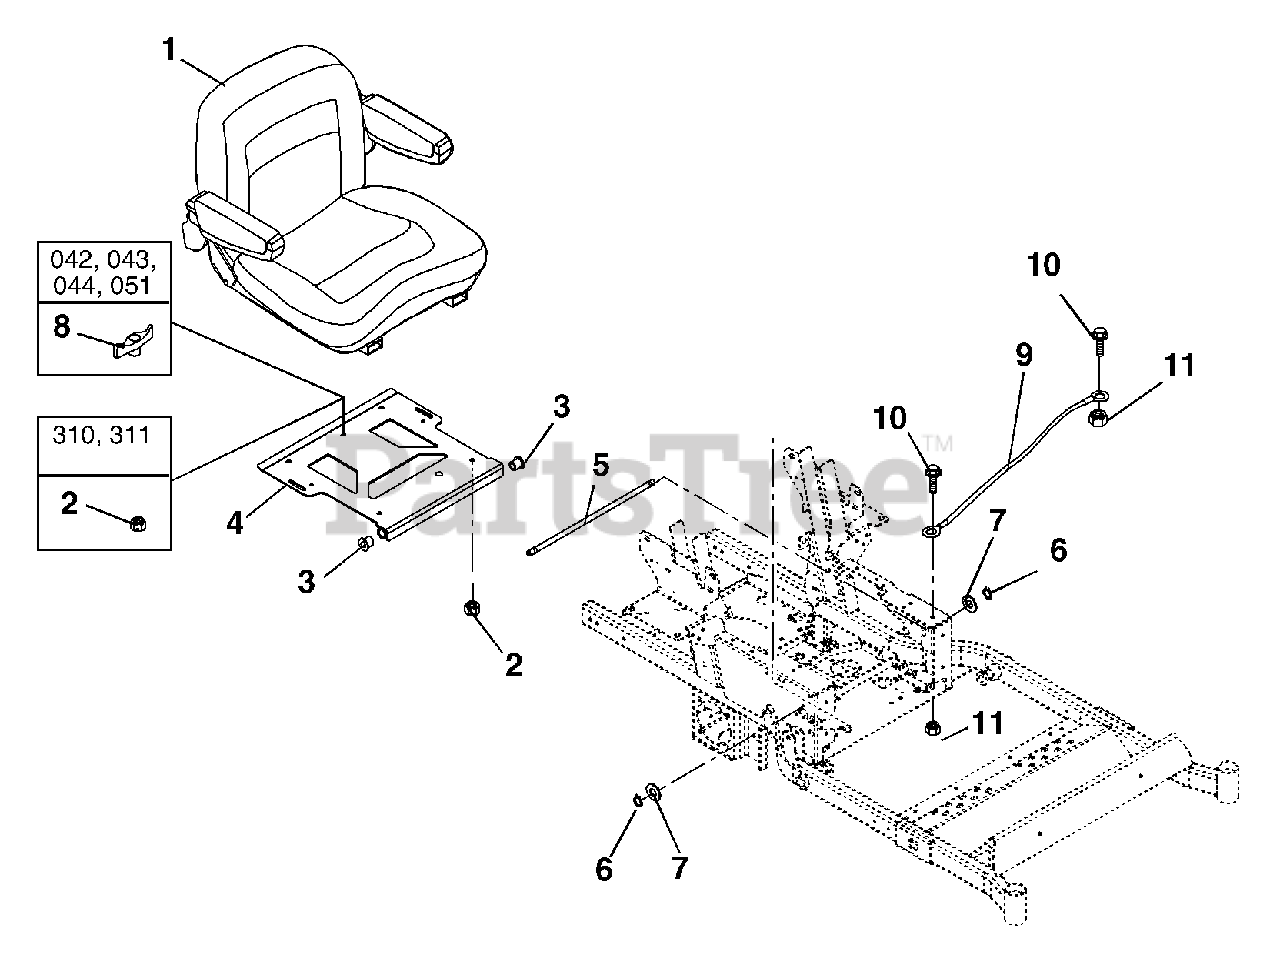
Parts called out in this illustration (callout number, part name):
2	Nut-Locking-Top-Flange .31-18 (042, 043, 044, 051)
2	Nut-Locking-Top-Flange .31-18 (310, 311)
3	Bushing-Flange .515 x .750 x .745 x 1.00
4	Seat Pivot Mount
5	Rod, Seat Frame Pivot
6	Ring-Retaining-External .500 x .050
7	Washer-Flat-Steel .531 x 1.06 x .095
8	Knob- Wing .312-18 (042, 043, 044, 051)
9	Cable, Hood
10	Bolt-Hex .25-20 x .75 Grade 5
11	Nut-Locking-Top-Flange .25-20
